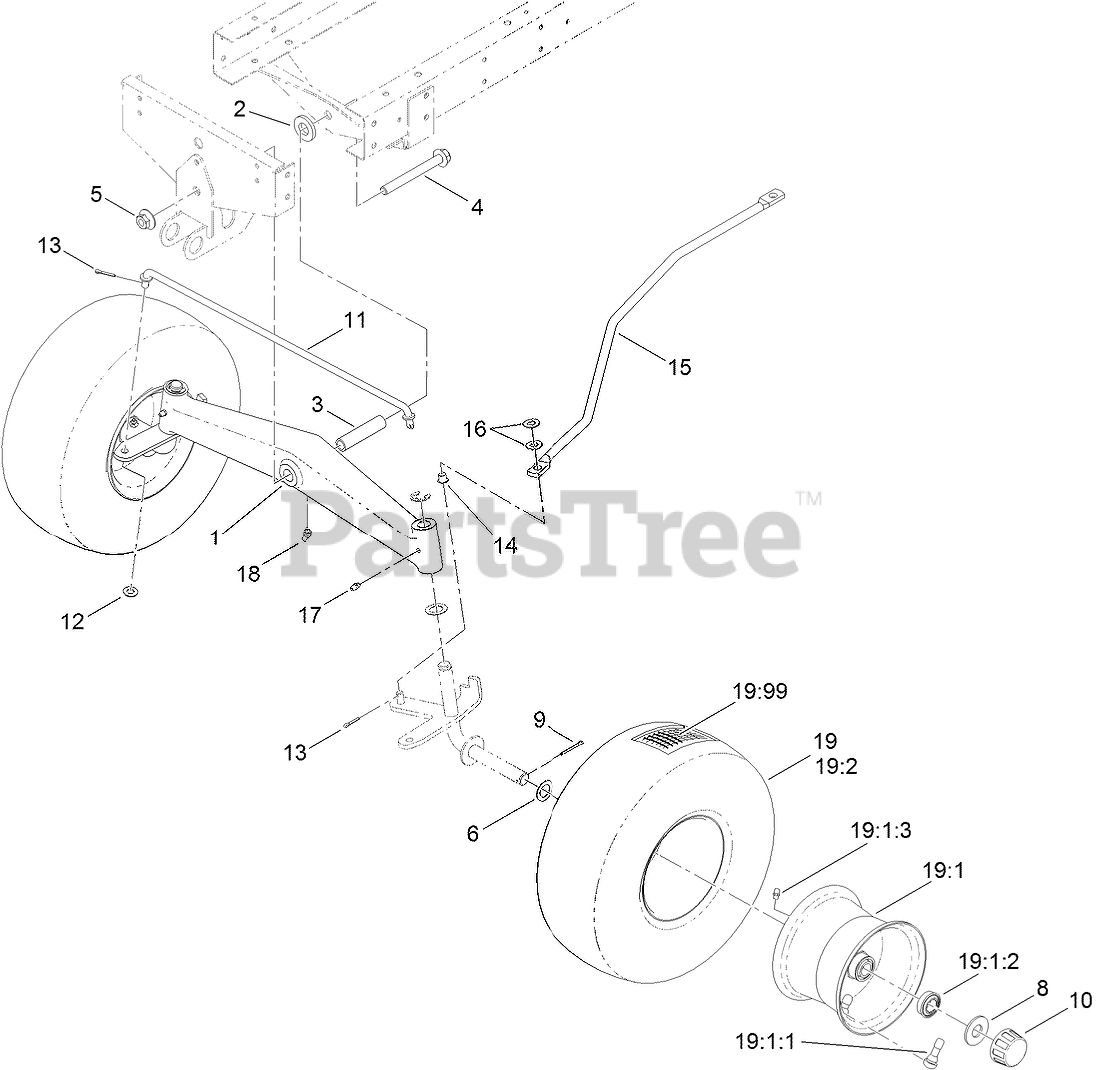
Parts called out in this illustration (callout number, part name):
1	FRONT AXLE ASM
2	BUSHING-FRONT, AXLE
3	TUBE-FRONT, AXLE
4	SCREW-HHF
5	NUT-HF
6	WASHER-THRUST
8	WASHER-PLAIN
9	PIN-COTTER
10	CAP-HUB
11	TIE ROD-STEERING
12	WASHER-FLAT
13	PIN-COTTER
14	BUSHING-FLANGED, NYLON
15	LINK-DRAG
16	WASHER-FLAT
17	FITTING-GREASE
18	FITTING-LUBE, 45 DEG
19	WHEEL AND TIRE ASM
19:1:1	STEM-VALVE
19:1:2	BEARING-WHEEL
19:1:3	FITTING-GREASE
19:99	TUBE-INNER
